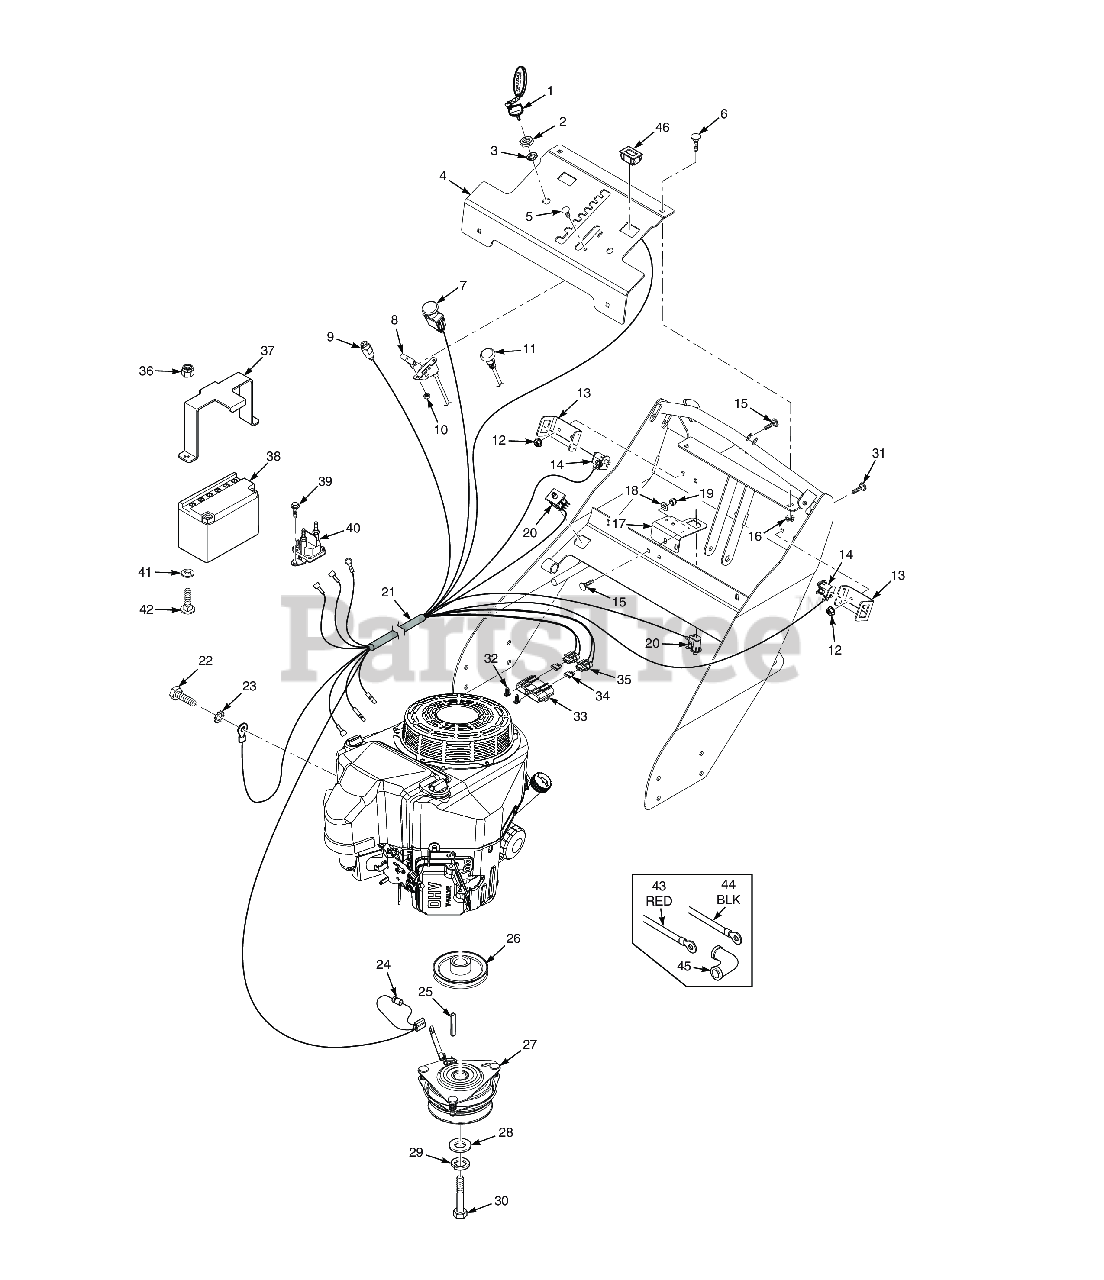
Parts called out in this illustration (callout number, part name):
1	Key, Assembly w/Fob
1	Key w/Shroud Only
2	Nut, 5/8-32 Special
3	LOCK WASHER, 5/8" INTERNAL TOOTH
4	Instrument Panel w/Decal
5	Bolt, Carriage #10-24 x 1/2"
6	Bolt, 5/16-18 x .75 RHSN Carriage
7	Switch, PTO - 10 Amp
8	Throttle Cable
9	KEY SWITCH(INCLUDES MOUNTING HARDWARE)
10	Nut, Elastic Stop #10-24
11	Choke Control
12	NUT, 1/4-20 SERRATED FLANGE HEX HEAD
13	Bracket, Operator Presence Switch
14	SWITCH, NEUTRAL INTERLOCK
15	Serr. Fl. Hex Head CPSCR, 1/4-20 x 3/4"
16	Nut, Serrated Flange 5/16-18 (Right Front Engine Mounting, Briggs and Kohler Only)
17	Bracket, Neutral Switch (Electric Start Only)
18	Flatwasher, 5/16-.375 x .875 x .083 (35BV & 37BV-EFI)
19	HEX, NUT, ELASTIC STOP LOCK, 1/4-20
20	Switch, Double Pole - Plunger
21	Wire Harness
22	Bolt, Hex Hd. M8-1.25 x 14mm
23	Lockwasher, 5/16" Ext. Tooth (Kohler x1)
24	Diode, 600V 6 Amp
25	KEY, 1/4 X 1/4 X 2-1/2"
26	Pulley, 4-1/2" Dia. - 1" Bore
27	Electric Clutch Assembly
28	Flatwasher, 7/16-.469 x 1.75 x .25 (48, 52)
29	Lockwasher, 7/16� Spring
30	Bolt, Hex Head 7/16-20 x 3" w/t Patch
31	Bolt, Carriage, 1/4-20 x 1-1/4"
32	Clip, Fuse Holder
33	Cover, Sealed Double
34	FUSE, 20 AMP BLADE TYPE AUTOMOTIVE
35	Fuse Holder Assembly
36	HEX NUT, ELASTIC STOP LOCK, 5/16-18
37	Bracket, Battery
38	Battery (not available through Scag)
39	Screw, Self-Tapping 1/4-20 x 3/4
40	Solenoid, Sealed (Briggs & Stratton)
41	Nut, Push-On 5/16-18
42	Bolt, Carriage 5/16-18x1" (large frame units only)
43	Battery Cable, Red 9" (Briggs & Stratton)
44	Cable, Battery - Black
45	RUBBER BOOT
46	Hour Meter, Inductive
